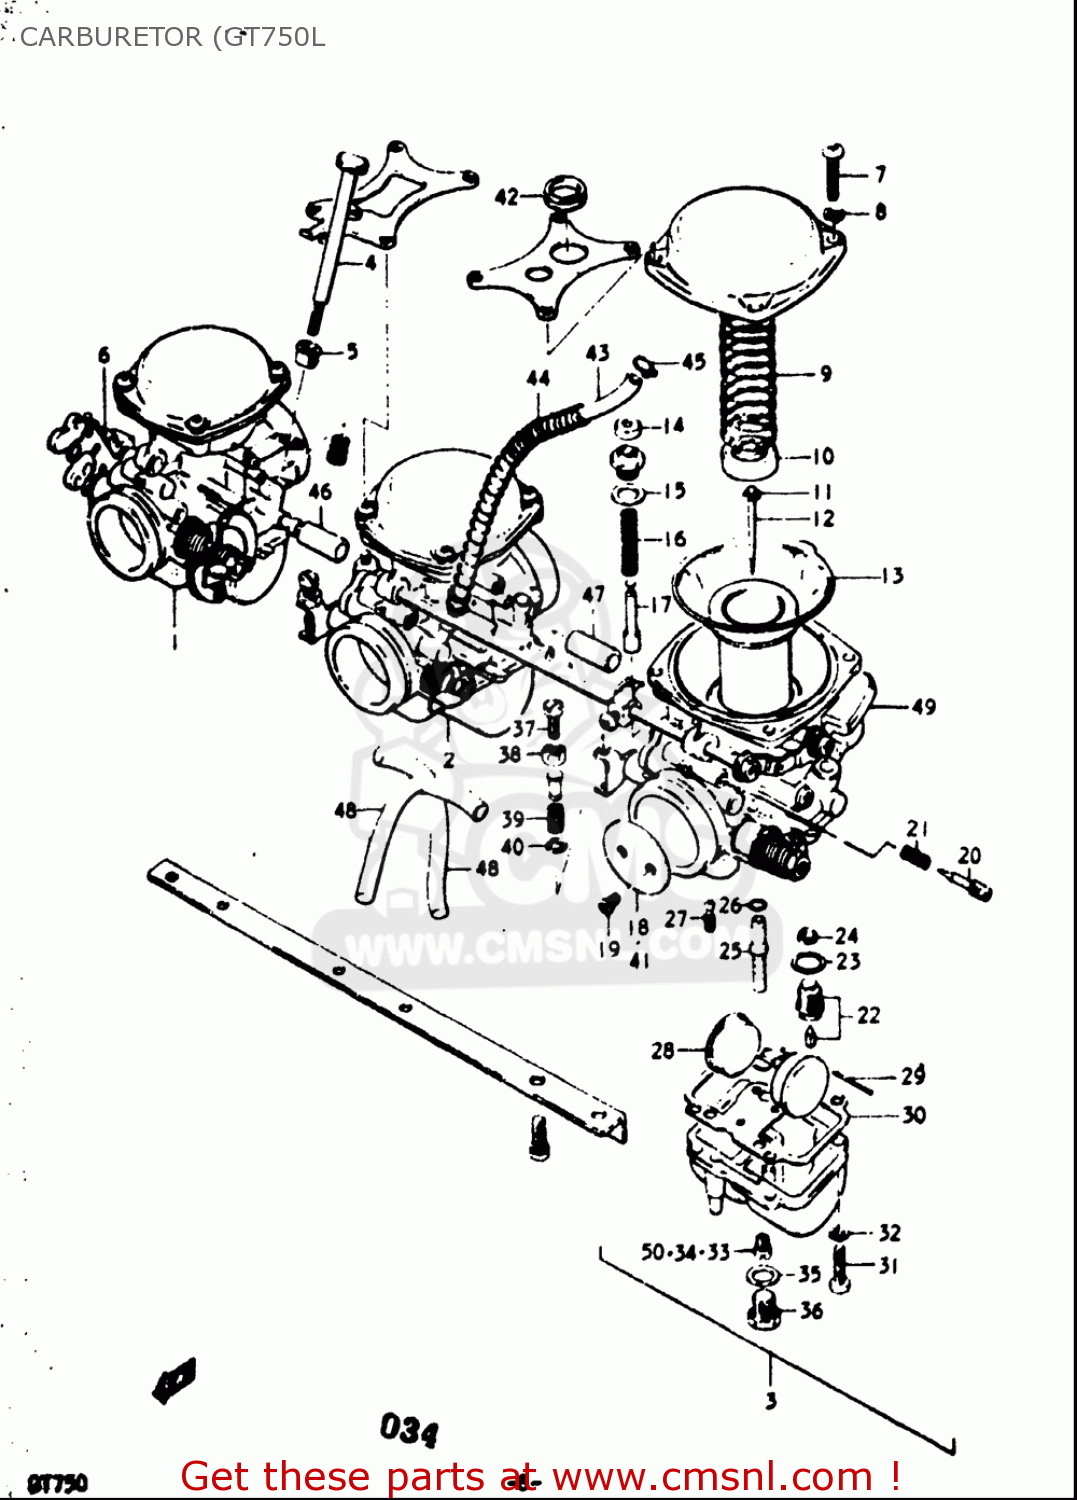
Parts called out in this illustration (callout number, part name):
5	BUSH
7	SCREW
8	WASHER,LOCK
11	CLIP,NEEDLE
12	NEEDLE,JET
13	DIAPHRAGM ASSY
14	CAP,STARTER VALVE
16	SPRING
19	SCREW
21	SPRING
22	VALVE ASSY,NEEDLE
23	GASKET,MAIN JET HOLDER (NAS)
24	FILTER
25	JET,NEEDLE
26	O RING(D:1.05,ID:3.1)
27	JET,PILOT
28	FLOAT
29	PIN,FLOAT
30	GASKET,FLOAT CAHMBER (NAS)
31	SCREW
32	WASHER,LOCK
33	JET,MAIN 107,5
34	JET,MAIN(110)
39	SPRING,THROTTLE SCREW
43	HOSE(4.5X8.5X600)
45	CLIP
46	HOSE
47	HOSE
50	JET,MAIN(100)
